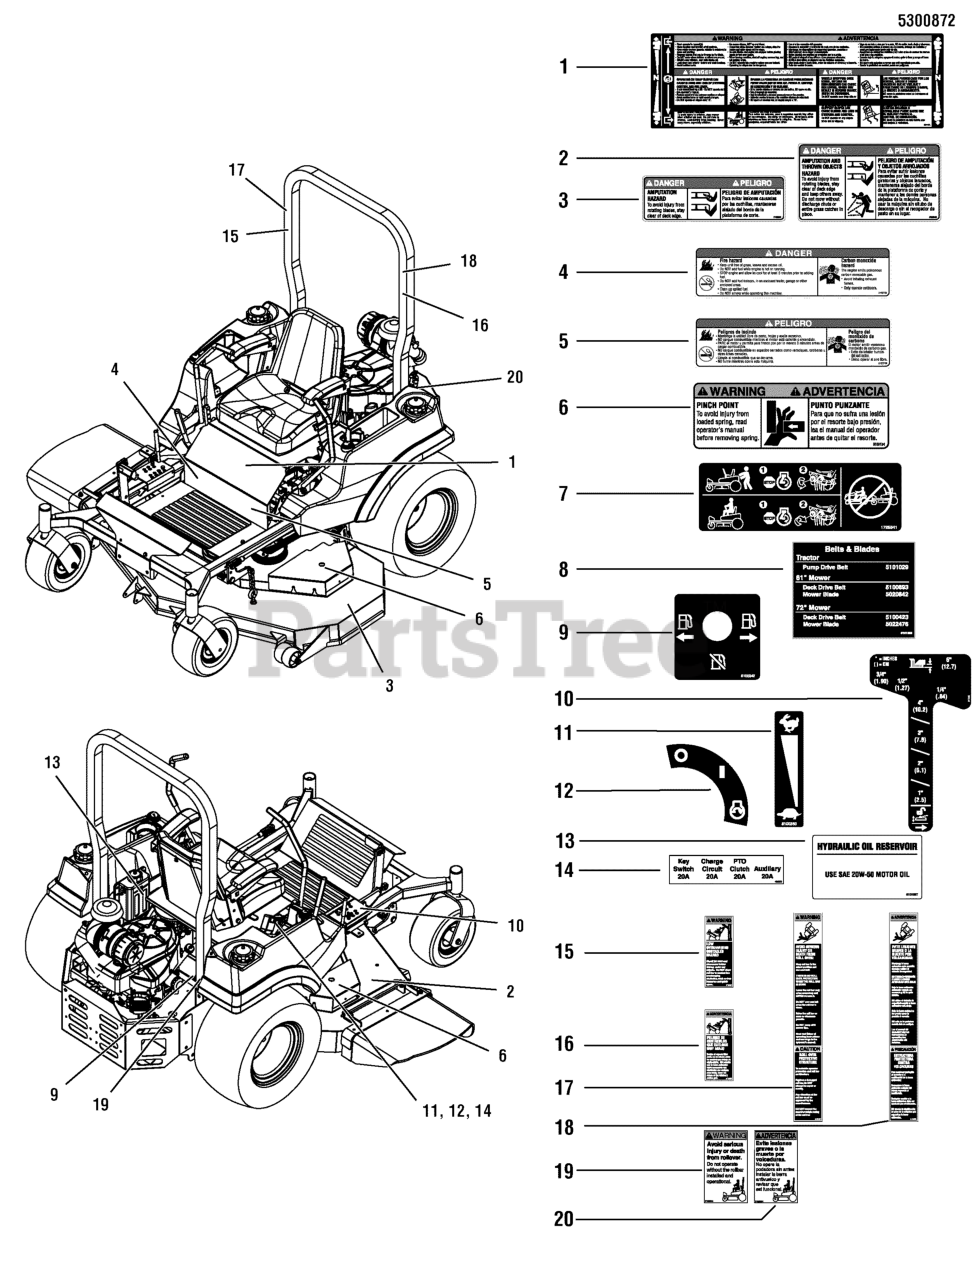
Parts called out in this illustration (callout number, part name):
1	DECAL, MAIN SAFETY
2	DECAL, DANGER, MOWER DISCHARGE
3	DECAL, DANGER, MOWER
4	DECAL, DANGER, FIRE
5	DECAL, DANGER, FIRE (SP)
6	DECAL, WARNING, PINCH POINT
7	DECAL, CZT HYDRO RELEASE
8	DECAL, BELT & BLADE, SNAPPER PRO 61/72
9	DECAL, FUEL VALVE
10	DECAL-HEIGHT CITATION
11	DECAL, THROTTLE CONTROL
12	DECAL, IGNITION SWITCH
13	DECAL, OIL RESEVOIR
14	DECAL, FUSE LOCATION
15	DECAL, WARNING, ROLL BAR (SV)
19	DECAL, WARNING, ROLL BAR
20	DECAL, WARNING, ROLL BAR, SP
